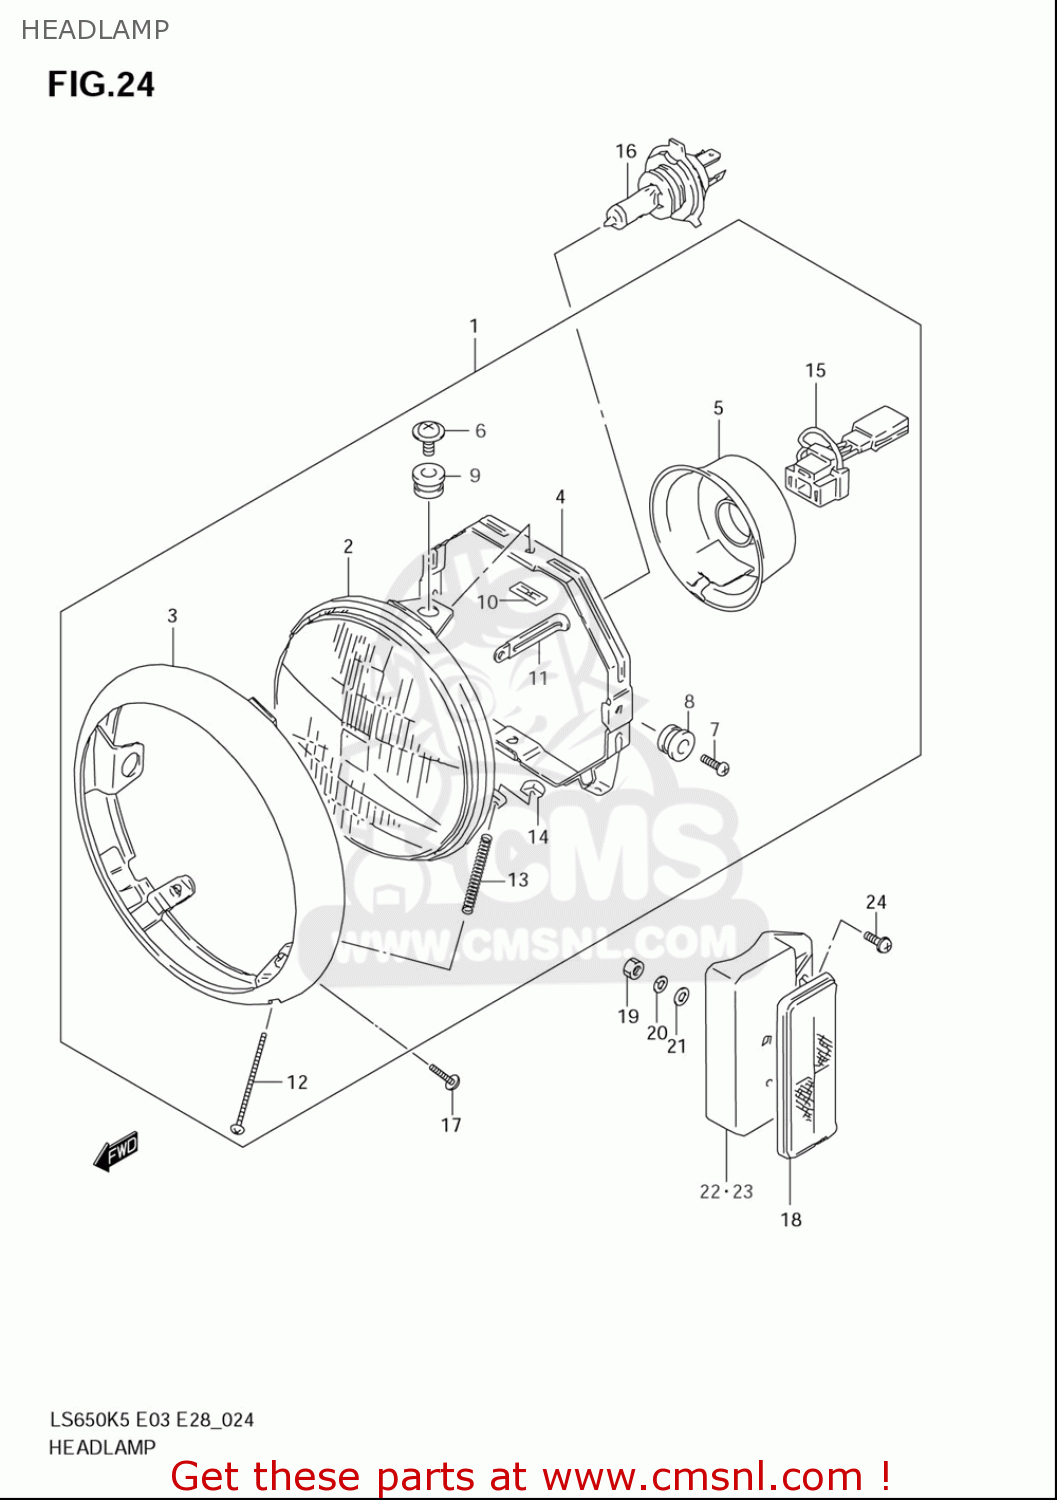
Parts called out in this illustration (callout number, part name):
1	HEADLAMP ASSY
2	UNIT,LAMP
3	RIM
4	RING,MOUNTING
5	COVER
6	SCREW
7	SCREW,MOUNTING
8	CUSHION
9	CUSHION
10	NUT
11	CLAMP(L:65)
12	SCREW,ADJUSTING(4X50)
13	SPRING
14	NUT,HEADLAMP ADJUST
15	SOCKET
16	BULB(12V60/55W,H4)
17	SCREW
18	REFLEX REFLECTOR,FR SIDE
19	NUT
20	LOCK,WASHER
21	WASHER(5.5X16X1.2)
22	BRACKET,FR SIDE RR,R
23	BRACKET,FR SIDE RR,L
24	SCREW(5X12)
